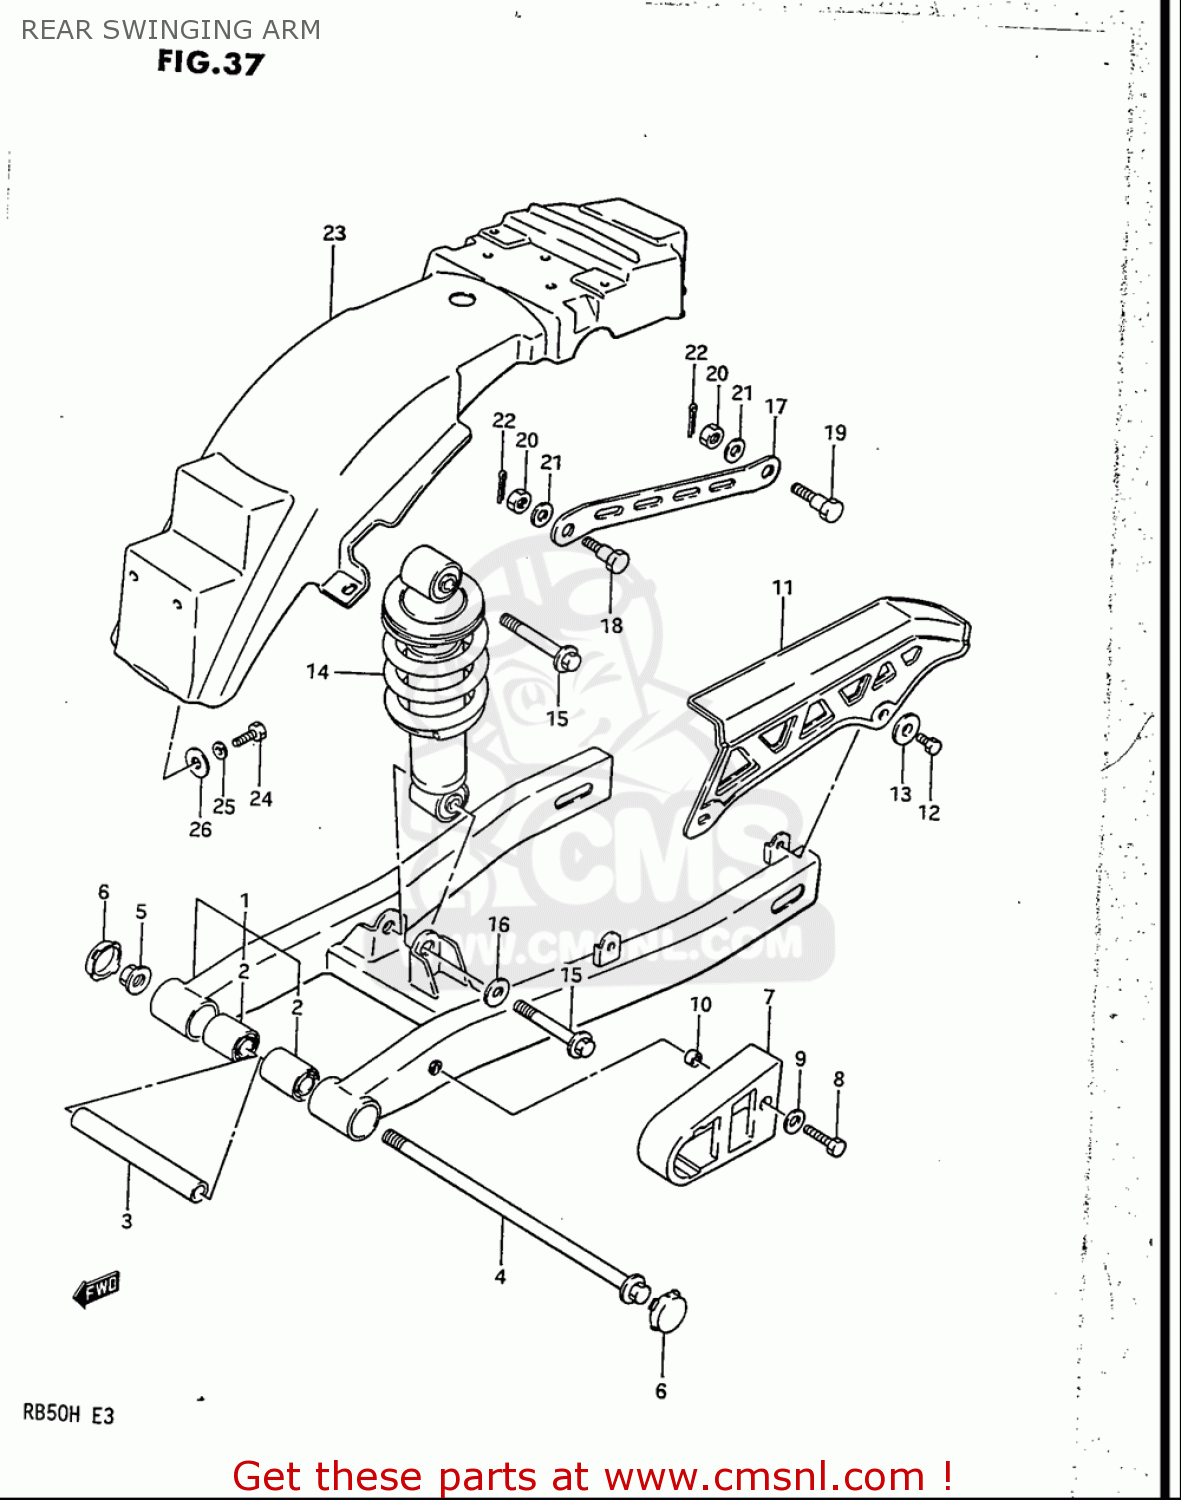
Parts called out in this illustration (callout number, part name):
2	BUSHING(10X23X35)
4	SHAFT,REAR SWING ARM PIVOT
5	NUT
7	BUFFER,CHAIN TOUCH DEFLECTOR
8	BOLT
9	WASHER(6.5X16X1.2)
10	SPACER(6.5X9X3.8)
11	CHAIN CASE
12	BOLT(6X8)
13	WASHER
15	BOLT,RR SHOCK ABSORBER(10X51)
16	WASHER
18	BOLT(8X22)
19	BOLT(8X26.5)
20	NUT
21	WASHER,LOCK
22	PIN
23	FENDER,REAR
24	BOLT
25	WASHER,LOCK
26	WASHER(6.5X20X1.2)
